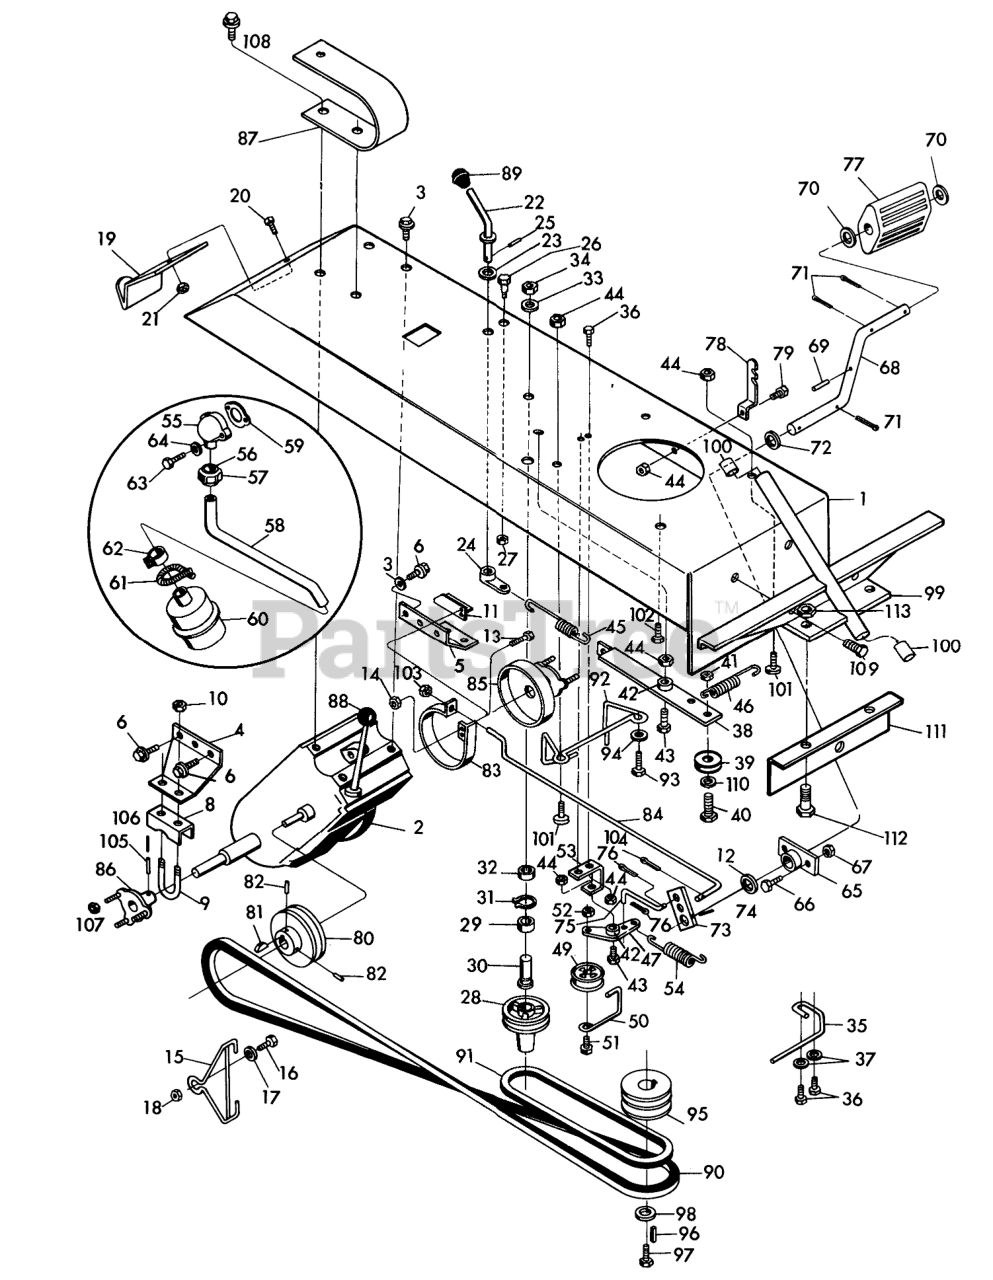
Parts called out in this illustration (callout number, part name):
1	Chassis
2	Transmission
3	Sems Screw
4	Right Wheel Bracket
5	Left Wheel Bracket
6	Screw & Washer
7	Washer
8	Axle Bracket
9	U-Bolt
10	Nut
11	Brake Mounting Bracket
12	Washer
13	SCREW-HH
14	Nut
15	Rear Belt Guide
16	SCREW-HH
17	Washer
18	Nut
19	Hitch
20	SCREW-HH
21	Nut
22	Blade Rod Assy
23	WASHER-SPRING
24	Lever
25	PIN-SPRING
26	SCREW-HH
27	Nut
28	Pulley
29	Bearing
30	Adapter
31	Snap Ring
32	Spacer
33	WASHER-LOCK
34	NUT-JAM
35	Belt Guide
36	SCREW-HH
37	WASHER-FLAT
38	Brake Arm
39	Pulley
40	SCREW-HH
41	NUT-JAM
42	Bushing
45	Spring
46	Spring
47	Clutch Lever (with bushing)
49	Pulley
50	Belt Retainer
51	SCREW-HH
52	NUT-JAM
53	Clutch Bracket
54	Spring
55	Manifold
56	Ferrule
58	Exhaust Pipe
59	Manifold Gasket
60	Muffler
61	Spring
62	Muffler Clamp
63	SCREW-HH
64	WASHER-LOCK
65	Clutch Arm
66	SCREW-HH
67	Nut
68	Clutch Arm
69	Roll Pin
70	Washer
71	PIN-COTTER
72	Washer
73	Clutch Arm
74	Roll Pin
75	Clutch Rod
76	PIN-COTTER
77	Pedal
78	Brake Strap
79	Shoulder Bolt
80	Pulley
81	KEY-WOODRUFF
82	Set Screw
83	Brake Band Assembly Consists of
84	Brake Rod
85	Hub L.H. (with brake drum)
86	Hub R.H.
87	Seat Spring
88	Knob
92	Belt Guide
93	SCREW-HH
94	WASHER-FLAT
95	Pulley
96	KEY-SQUARE
97	SCREW-HH
98	Washer
99	Steering Support
100	Bushing
102	SCREW-HH
103	NUT-LOCK, NI
104	PIN-COTTER
105	PIN-ROLL, SLOTTED
106	PIN-ROLL
107	LUG NUT
110	Washer
111	Axle Support
112	SCREW-HH
113	Nut
